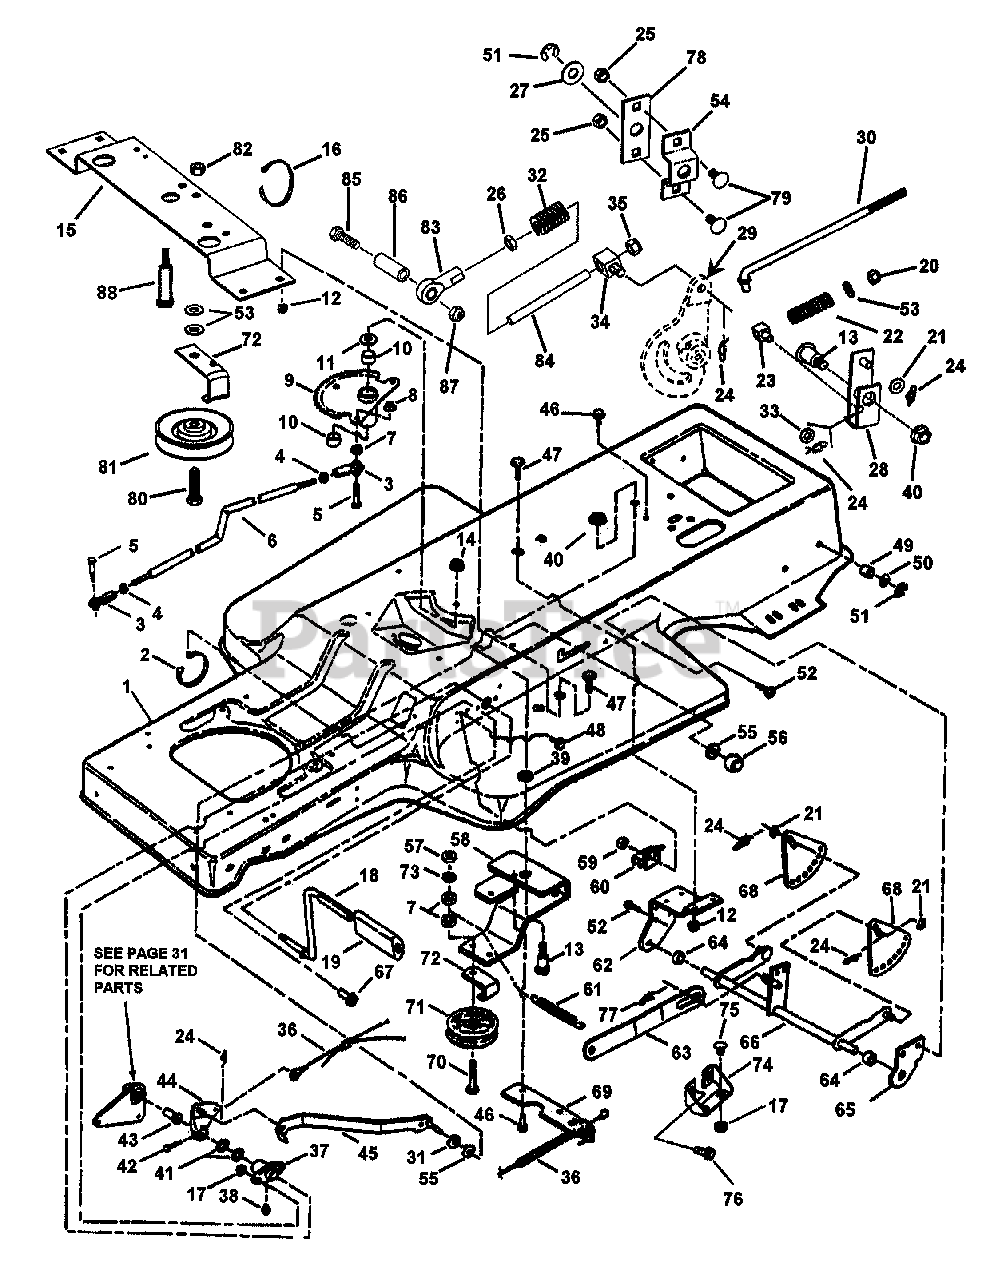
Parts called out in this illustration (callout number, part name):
1	FRAME, Tractor (1 piece)
2	TIE, Wire
3	BALL JOINT, 3/8-24 thread
4	NUT, 3/8-24 Hex Jam
5	SCREW, 3/8-24 x 1-1/4" Hex Cap
6	LINK, Drag
7	SPACER
8	NUT, 3/8-16 Hex Flange Lock
9	ASSEMBLY, Sector Gear
10	BEARING, Sector Gear
11	WASHER, 3/4" Thrust
12	NUT, 1/4-20 Hex Flange Lock
13	BOLT, 1/2-13 x 2" Shoulder
14	NUT, 1/2-13 Hex Center Lock Gr. A
15	BRACE, Sector Gear
16	TIE, Cable 7"
17	NUT, 5/16-18 Hex Flange Lock, Gr. 5
18	PEDAL, Clutch Brake
19	PAD, Pedal
20	NUT, 3/8-16 Hex Nyloc
21	WASHER, 3/8 Bright Zinc, Flat
22	SPRING, Brake
23	SWIVEL, Inline Brake
24	PIN, 3/8 x 1-7/32" Cotter (Self Locking)
25	NUT, 5/16-18 Hex Center Lock
26	NUT, 5/16-24 Hex Jam Lock
27	WASHER, 44" ID Flat
28	WELDMENT, Brake Arm
29	ARM, Speed Control
30	ROD, Brake
31	WASHER, 5/16" Flat
32	SPRING
33	WASHER, .406 I.D. Flat
34	SWIVEL, Brake Link
35	NUT, 5/16-24 Hex Top Lock
36	ASSEMBLY, Clutch/Brake Cable
37	ASSEMBLY, Foot Shaft Pivot
38	LUBE FITTING, Straight (press-fit for .187 dia. Hole)
39	WASHER, 1/2" Internal Tooth Lock
40	NUT, 1/2-13 Hex Flange Lock
41	WASHER, 5/8" Flat
42	PIN, 3/16 x 1-1/2" Clevis
43	BEARING, Flange
44	WELDMENT, Clutch Brake Arm
45	LATCH, Park Brake
46	SCREW, 5/16-18 x 5/8" Self-Tap
47	BOLT, 1/4-20 x 5/8" Carriage
48	SCREW, #10-32 x 5/8" Self-Tap
49	BUSHING, 1/2" Nylon
50	WASHER, 1/2" Flat
51	RING, 1/2" External Retaining
52	SCREW, 5/16-18 x 5/8" Truss
53	WASHER, 3/8" Flat
54	BRACKET, Pivot Mounting
55	WASHER, 5/16" Nylon
56	KNOB, Clutch/Brake (5/16-18)
57	NUT, 3/8-16 Hex, Grade B or 5
58	ARM, Idler (Traction Drive)
59	NUT, #10-32 Hex Nyloc
60	SWITCH, DPDT NC/NO
61	SPRING, Traction Drive
62	BRACKET, Rear Lift/PTO Lever
63	LINK, Lift (33" Deck)
63	LINK, Lift (38" Deck)
65	BRACKET, Deck Hang Pivot
66	WELDMENT, Rear Lift Arm (33" Deck)
66	WELDMENT, Rear Lift Arm (38" Deck)
67	SCREW, 5/16-18 x 7/8" Truss Head (Torx)
68	PLATE, Lift Sector
69	EXTENSION, Idler Arm
70	SCREW, 3/8-16 x 2-1/2" Cap Grade 5
71	PULLEY, Flat Idler, 3 47" O.D
72	GUIDE, Pulley
73	WASHER, 3/8" Split Lock
74	BRACKET, Frame Brace
75	BOLT, 5/16-18 x 5/8" Short Neck Carriage, Grade 5
76	SCREW, 5/16-18 x 3/4" Self-Tap
77	COTTER PIN, 1/16 x 1-7/32" Self Lock
78	BRACKET, Mounting Brace
79	BOLT, 5/16-18 x 3/4" Carriage
80	SCREW, 3/8-16 x 1-1/2" Cap, Grade 5
81	PULLEY, Idler V 3.30
82	NUT, 3/8-16 Hex Center Lock
83	BALL JOINT, 5/16-24
84	FOOD, Shift Linkage
85	SCREW, 5/16-18 x 1-1/2" Cap
86	SPACER
87	NUT, 5/16-18 Hex Center Lock
88	BOLT, 12-13X3-7/8" Shoulder
